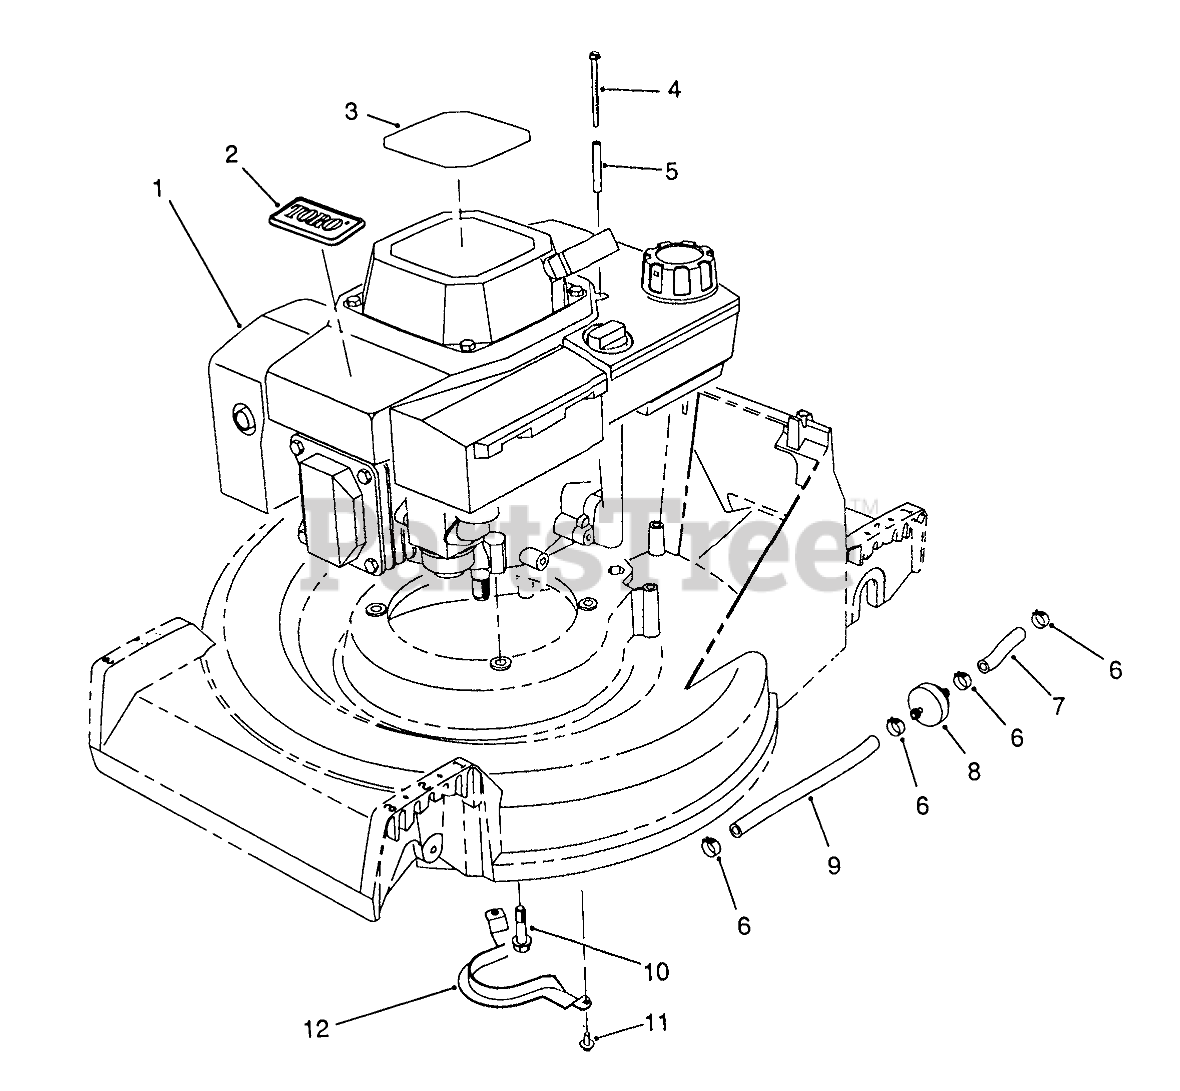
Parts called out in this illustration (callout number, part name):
1	ENGINE ASSY BBC OHV SU
2	TORO LOGO PLT
3	DECAL - OHV RECOIL
4	THRD FORMING SCREW
5	TUBULAR SPACER
6	CLAMP-FUEL LINE
7	LINE-GAS
8	FILTER-FUEL
9	HOSE-FUEL
10	SCREW-HWHTF
11	SCREW-HWHTF
12	Guide-Belt
